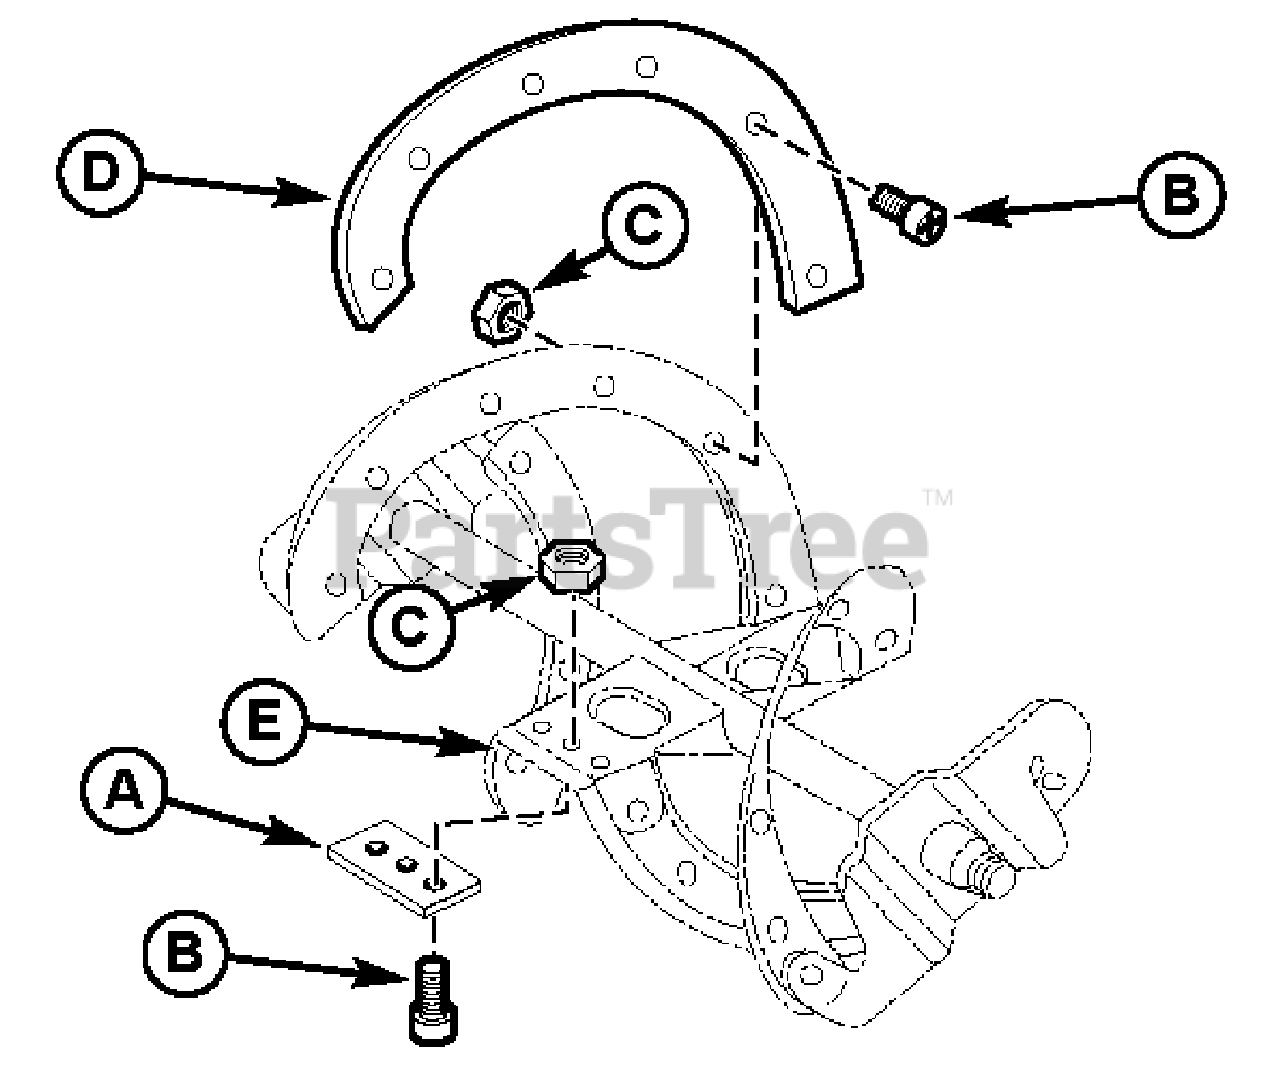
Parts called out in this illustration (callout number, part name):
A	Flighting, Center
B	Truss Head Screw, 1/4-20 x 3/4
C	Nut, 1/4-20, ESNA Lock
D	Flighting, Auger, Helix
